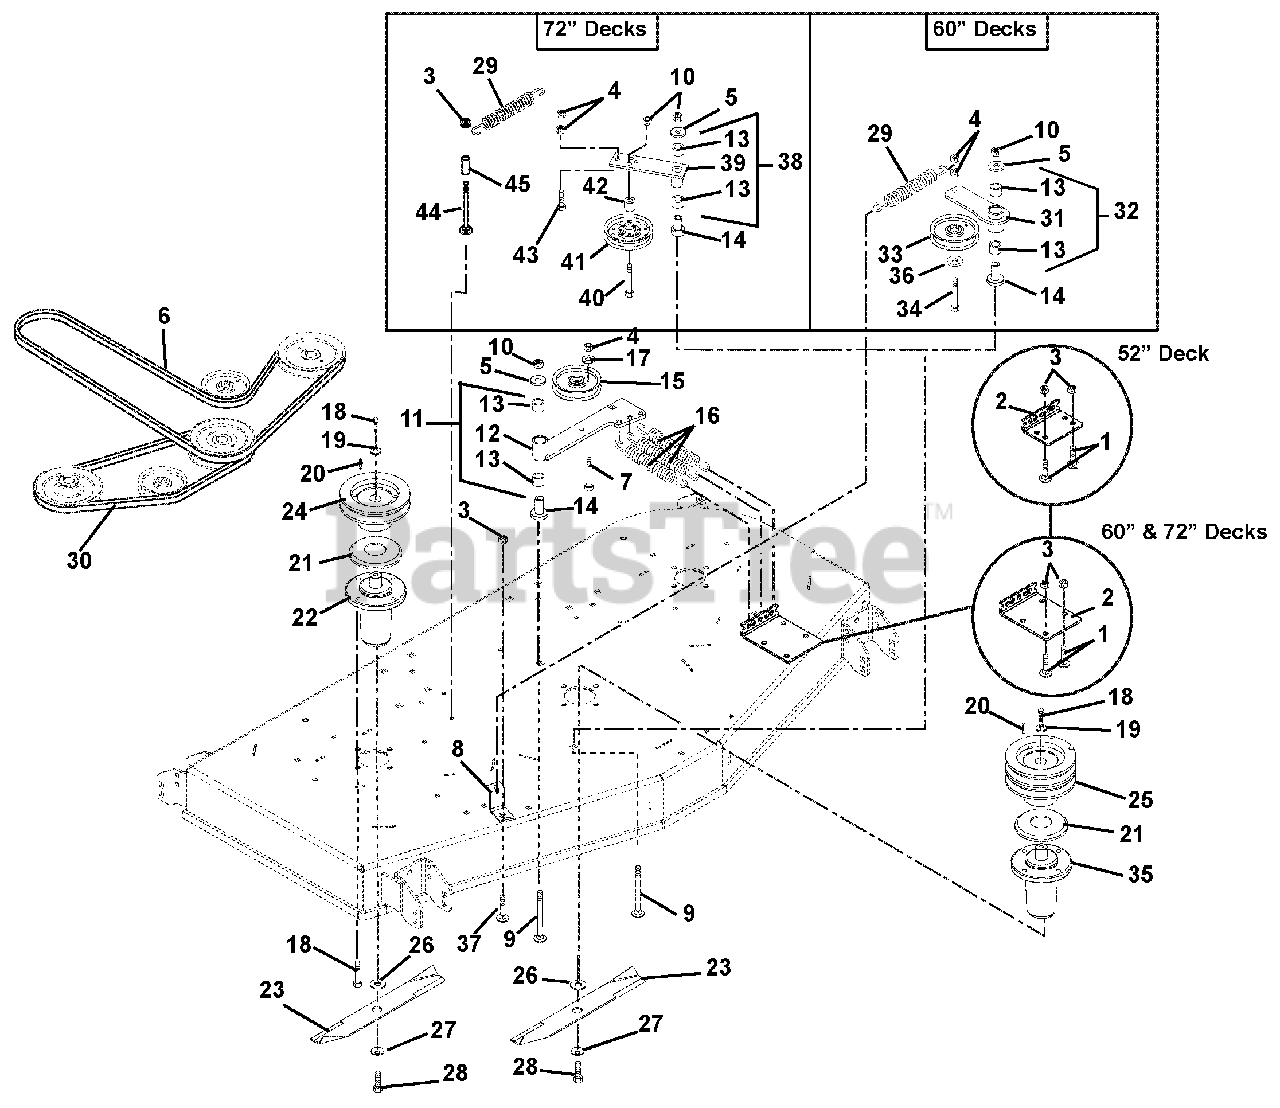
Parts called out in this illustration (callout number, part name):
1	Bolt, Round Head Square Neck .38-16 x .75 Grade 5
2	Bracket, Spring (316, 317, 321)
3	Nut, Locking Top Flange .38-16
4	Nut, Locking Center .38-16
5	Washer, Flat Steel .531 x 1.25 x .10
6	V-Belt, B-Section 54.06 x .625 (316, 317)
7	Bolt-Round Head Square Neck .38-16 x 2.75 Grade 5
8	Anchor, Spring
9	Bolt, Round Head Square Neck .50-13 x 3.50 Grade 5
10	Nut, Locking Top Flange .50-13
11	Assembly-Deck Idler Pivot Arm (Contains Items 12 & 13)
12	Weldment, Deck Idler Pivot Arm
13	Bearing, 1.00 x 1.12 x .75
14	Bearing, Pedestal Powdered Metal
15	Idler, Flat 4.00 x .38 (2.32W)
16	Spring, Extension Dia. 1.00 x 6.65LG
17	Washer, Flat Steel .375 x 1.125 x .065
18	Bolt, Hex .38-16 x 1.00 EP 30 Grade 8
19	Washer, Flat Steel .406 x 1.50x .245
20	Key, Square .25 x .25 x 1.00
21	Slinger, Dust
22	Assembly, Maintenance Free Spindle
23	Blade, Mower 60" Mulch (316, 317)
24	Weldment, Spindle Sheave 6.00
25	Sheave, Double (6.25)
26	Washer, Flat .64 x 1.81 x .25
27	Washer, Bellville .63 x 1.625 x .14
28	Bolt, Hex .62-18 x 1.75 Grade 8
29	Spring, Extension
30	V-Belt B-Section 23.94 x .625
31	Arm, Idler Pivot
32	Asm, Idler Pivot Arm (Contains Items 13 and 32)
33	V-Idler, 4.00 x .38 (060, 075)
34	Bolt, Hex .38-16 x 2.25 Grade 5
35	Spindle Assembly (Center)
36	Washer, Flat Steel .406 x .812 x .05
37	Bolt, Round Head Square Neck .38-16 x 1.00 Grade 5
38	Assembly, Idler Arm Guard Drive (Includes Items 13 and 39) (321)
39	Weldment, Idler Arm Ground Drive (321)
40	Bolt, Hex .38-16 x 6.00 Grade 5 (321)
41	Idler, Flat Pulley 6.75 xz .51 (321)
42	Spacer .513 x .748 x .62 (321)
43	Bolt, Hex .38-16 x 1.25 Grade 5 (321)
44	Bolt, Round Head Square Neck .38-16 x 2.75 Grade 5 (321)
45	Spacer .38 x .625 x 1.50 (321)
